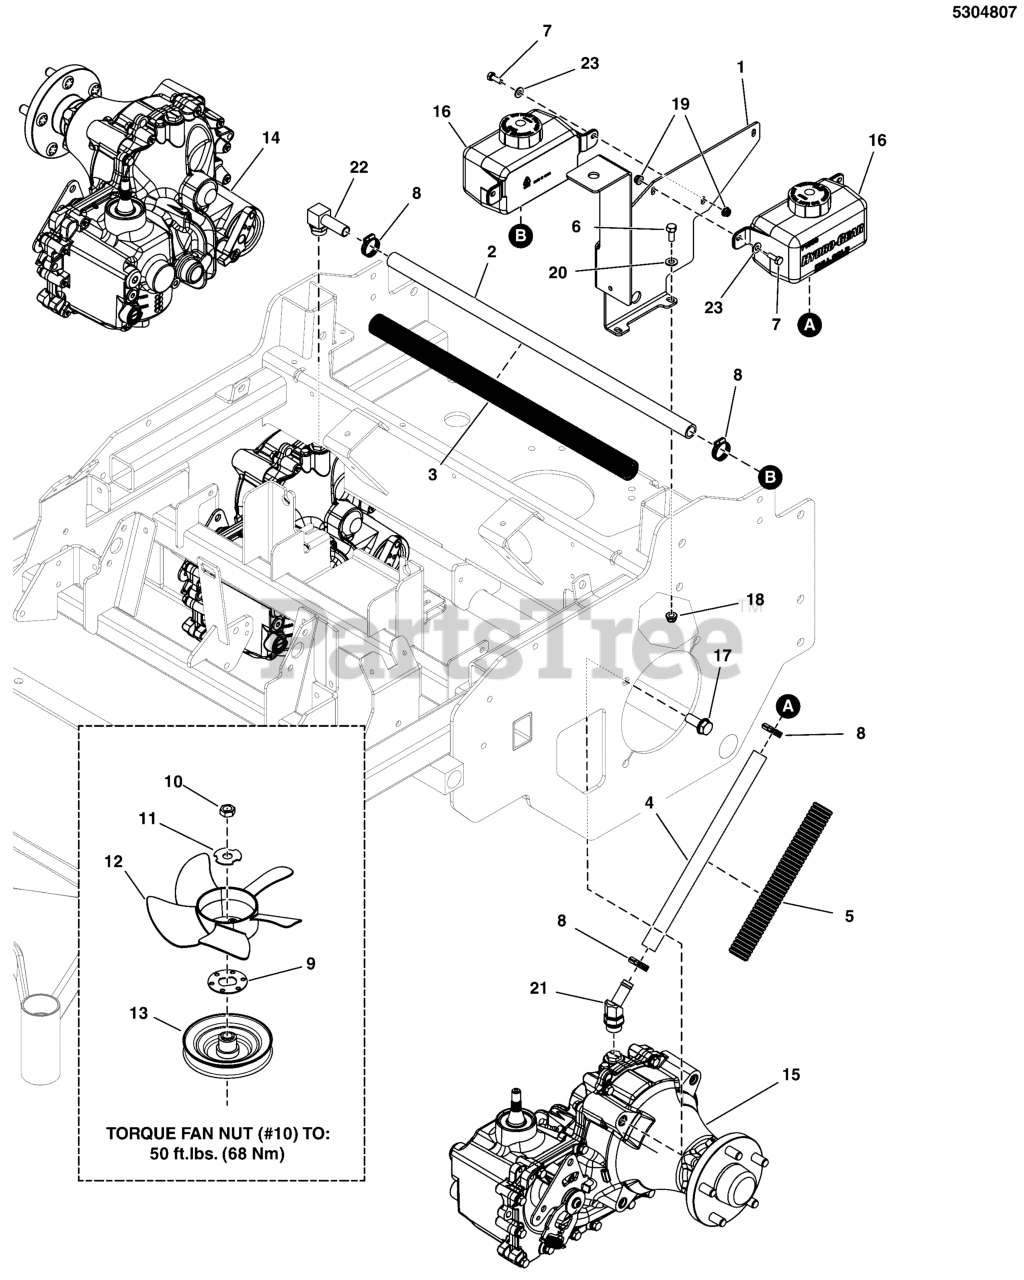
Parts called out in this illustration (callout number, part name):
1	PLATE, HYDRO MOUNT - OG, S200XT - BLK
2	HOSE, 5/8, PUSH-LOCK, 28.00
3	LOOM, CONVOLUTED SPLIT, 1 ID - 23 LONG
4	HOSE, 5/8 PUSH-LOCK, 13.00"
5	LOOM, CONVOLUTED SPLIT, 1 ID - 10 LONG
6	BOLT, 5/16-18 X 3/4 GD5
7	BOLT, 1/4"-20 X 3/4" GD5 YZ
8	CLAMP, #10 HOSE, STAINLESS
9	SPACER, ANTI-ROTATE, ZT5400
10	NUT, ZT5400
11	WASHER, ZT5400, SLOTTED
12	FAN, ZT5400
13	PULLEY, ZT5400 (53177)
14	TRANSAXLE, ZT5400, RH, 1015-1057R L AXLE
15	TRANSAXLE, ZT5400, LH, 1015-1057L L AXLE
16	HYDRO TANK, HYDRO-GEAR 71938, 1 LITER
17	BOLT,HEX FLG,SER,GD8 1/2-13X1-1/4W/PATCH
18	NUT, 5/16-18 HEX NYLOCK FLANGE NUT
19	NUT, 1/4-20 Hex Nylock Flange
20	WASHER, 5/16" SAE
21	FITTING, 45, 5/8 TUBE TO 7/8-14 O-RING
22	FITTING, EBLOW, 7/8-14 O-RING-5/8" TUBE
23	WASHER, 1/4 SAE
